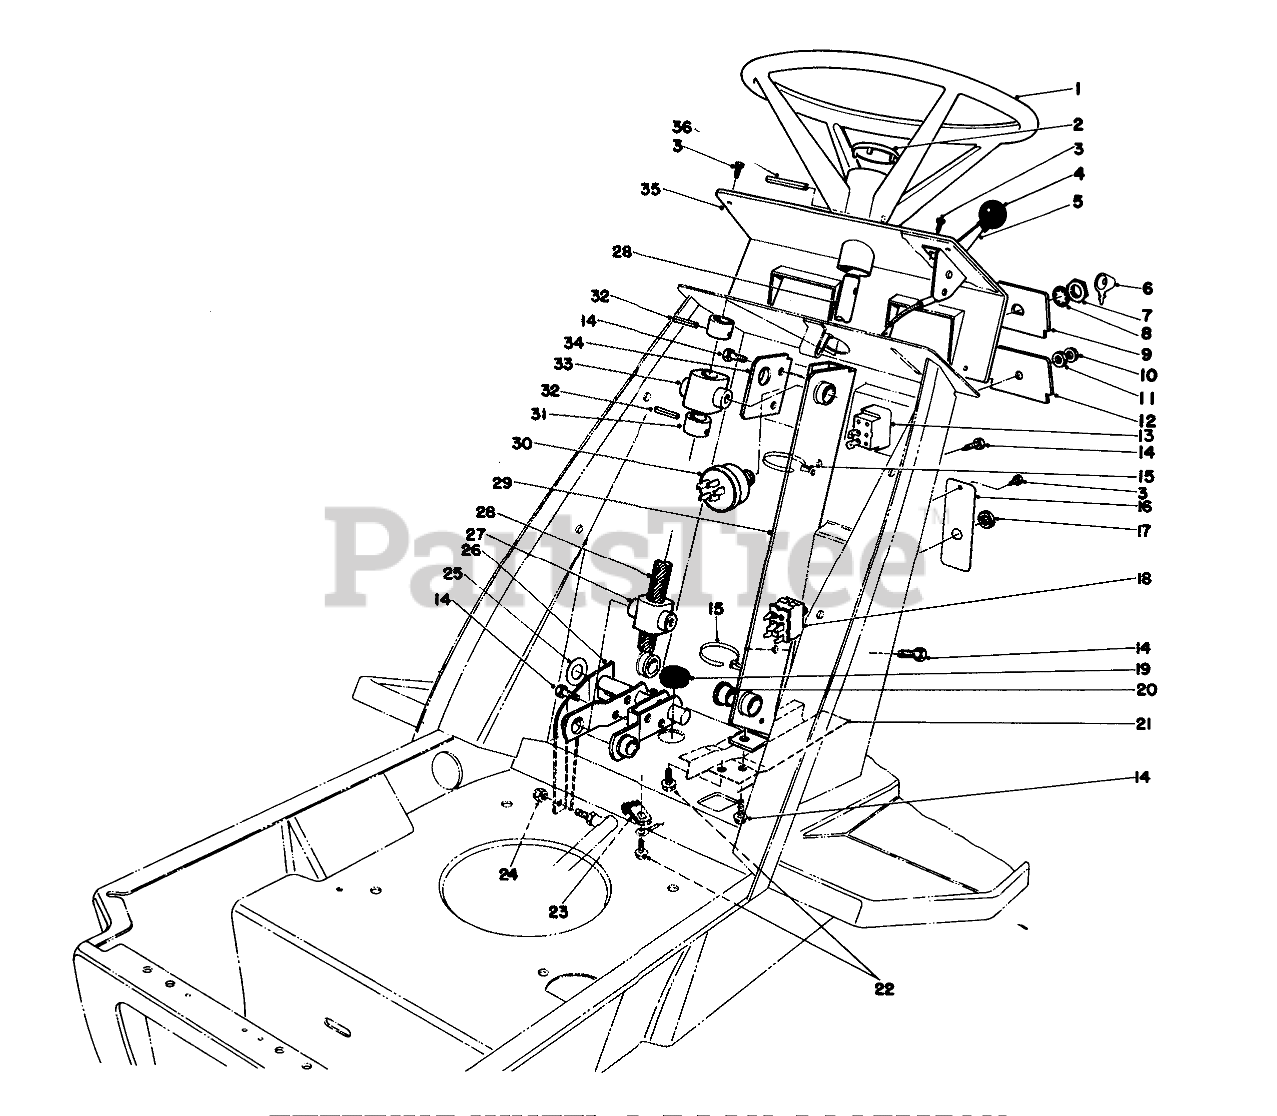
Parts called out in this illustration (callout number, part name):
1	Steering Wheel Assembly (Incl. Ref. #2)
2	Cap-Steering Wheel
3	SCREW-HWHTF
4	KNOB-CONTROL
5	Throttle Control (Incl. Ref. #4)
6	Key
7	NUT-HH
8	WASHER-TOOTH, INTERNAL
9	DASH PANEL INSERT
10	NUT-BULB
11	NUT-LOCK
12	DASH PANEL INSERT
13	Light Switch (Incl. Ref. #10 & 11)
14	SCREW-HWHTF
15	Cable Tie (Incl. w/Wire Harness)
16	CLUTCH PLT SWITCH
17	NUT
18	Switch-Clutch (Incl. Ref. #17)
19	Grommet (Incl.w/Wire Harness)
20	BEARING-FLANGE
21	WIRE HARNESS SHLD B
22	SCREW
23	CLIP-FUEL LINE
24	NUT-HEX
25	WASHER
26	STEERING LINK WA BO
27	FOLLOWER STEER SHAFT
28	STEERING SHAFT
29	STRG BRKT B
30	Ignition Switch (Incl. Ref. #6-8)
31	STRG SHAFT COLLAR
32	PIN-SPRING
33	BRG STEERING SHAFT
34	STRG BRG SUPPORT
35	DASH PANEL
36	PIN-ROLL
